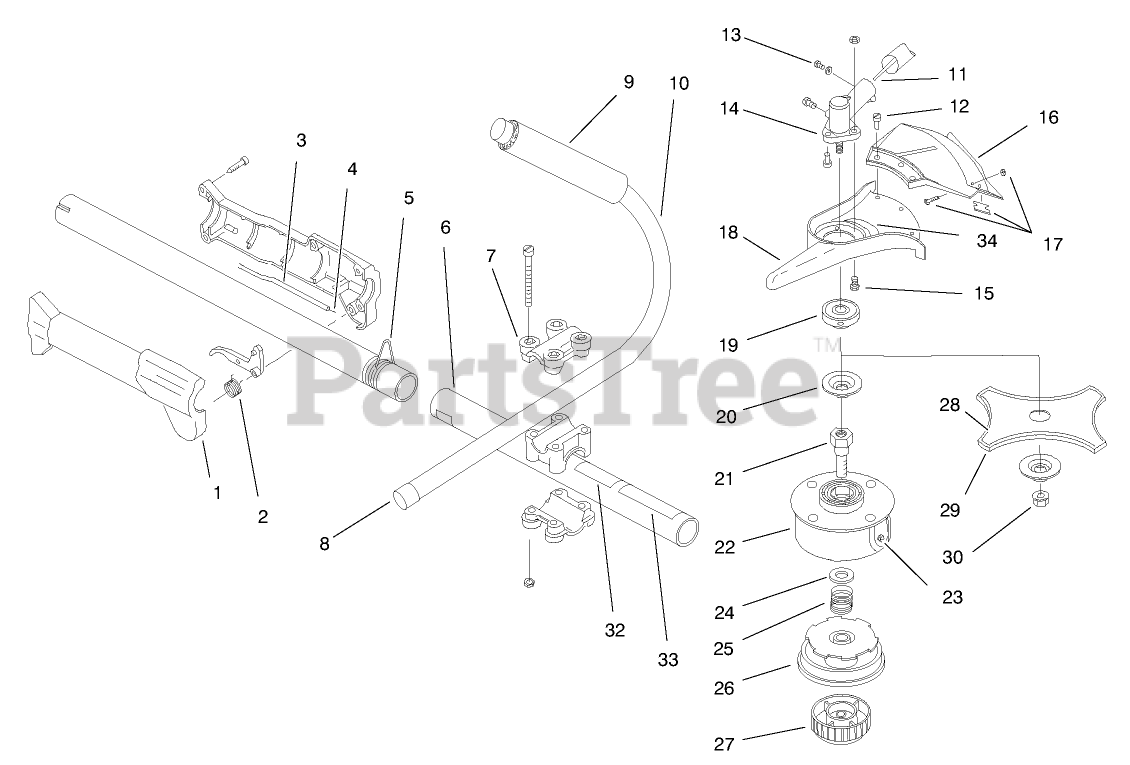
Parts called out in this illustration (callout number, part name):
1	ASM-THROTTLE HSG/TRIGGER
2	THROTTLE TRIGGER SPRING
3	Throttle Cable Housing
4	WIRE-THROTTLE
5	Clip-Shoulder Strap
6	DRIVE SHAFT HSG ASM
7	HANDLE BRACKET ASM
8	TUBE CLOSURE
9	HANDLE NITRILE GRIP
10	J-Handle Asm. (Incl. Ref. #8-9)
11	SHAFT - FLEXIBLE DRIVE
12	SCREWS - GUARD MOUNTING
13	MTG HDW&PLUG SET
14	Gear Box Asm. (Incl. Ref. #13, 19, 20, 30)
15	GUARD MNTG SCREW ASM
16	Guard and Blade Asm. (Incl. Ref. #17)
17	BLADE ASM
18	GUARD MOUNT
19	BLADE DRIVER
20	Blade Retaining Washer
21	SPOOL SHAFT
22	Outer Spool & Eyelet Asm.
23	EYELET
24	RETAINER ( 10 PACK)
25	SPRING
26	INNER REEL
27	BUMP HEAD KNOB ASSEMBLY
28	Blade
29	BLADE SAFETY GUARD
30	BLADE RETAINER NUT
32	Decal-Safety Symbol
33	DECAL - SAFETY
34	DECAL - WARNING
